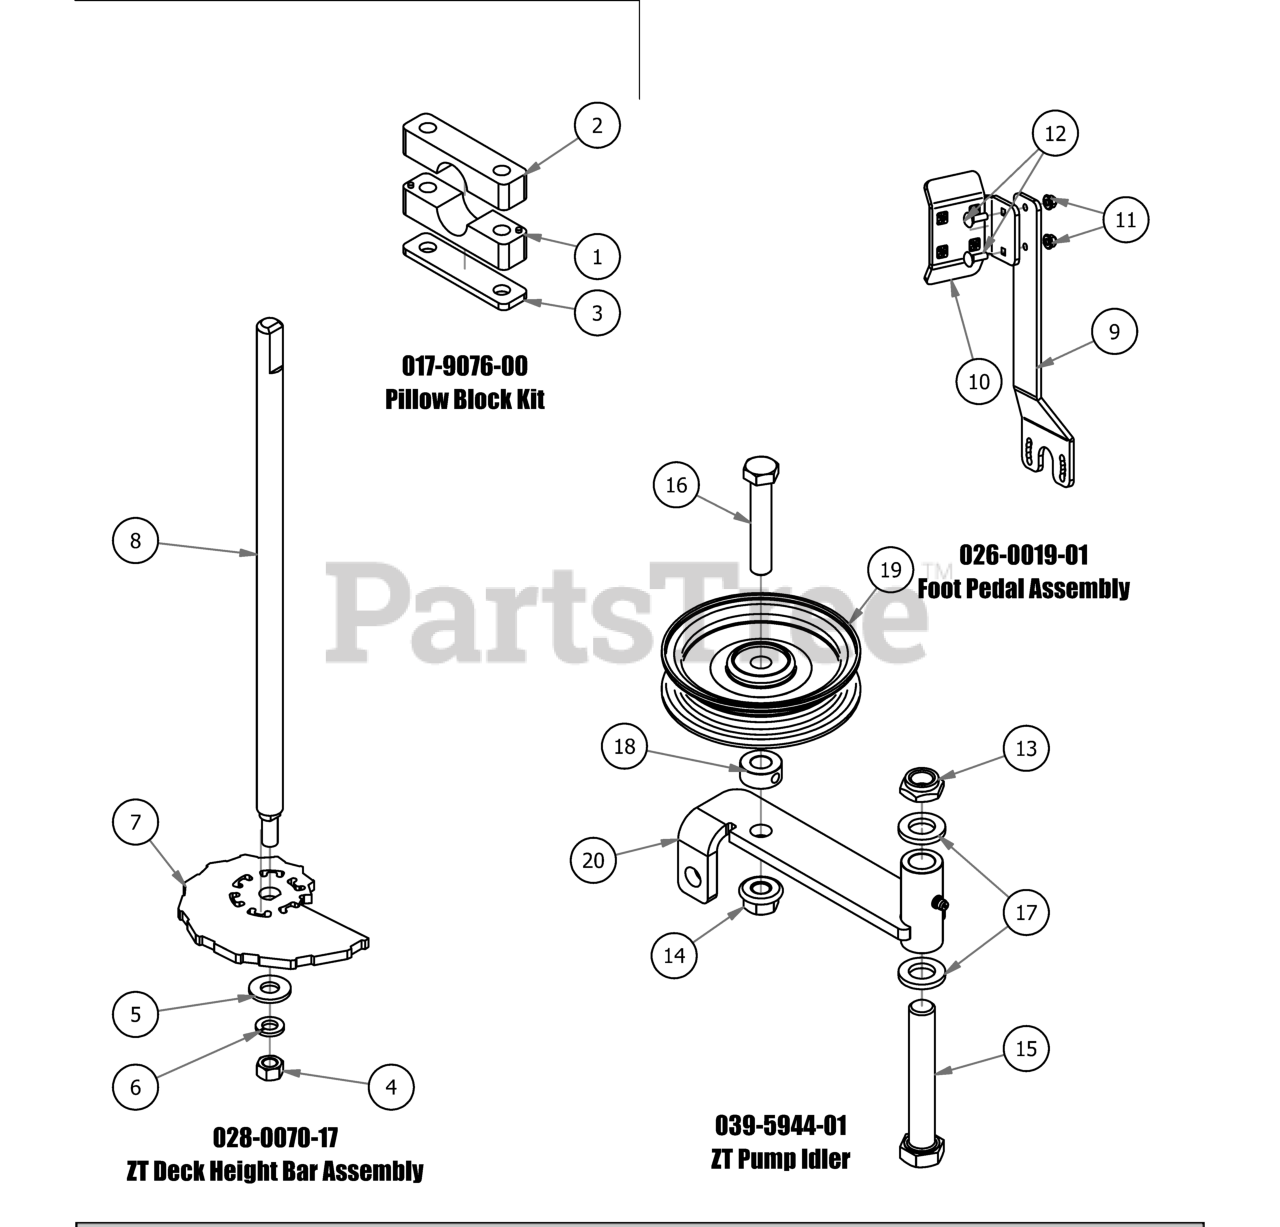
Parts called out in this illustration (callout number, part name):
1	Pillow Block MZ male
2	Pillow Block MZ female
3	Pillow Block Strap
4	3/8" Fine Threaded Jam Nut
5	3/8" Flat Washer
6	3/8" Lock Washer
7	2017 MZ/ZT Cam Plate
8	2017 Deck Height Dial Rod ZT
9	2017 MZ/ZT Deck Pedal Lever
10	2017 MZ/ZT Shallow Foot Pedal
11	5/16" Nylon Flange Nut
12	5/16" x 1" Carriage Bolt
13	5/8-11 NYLON INSERT JAM LOCKNUT ZINC
14	1/2-13 NYLON INSERT FLANGE LOCKNUT ZINC
15	5/8-11 X 4 HEX CAP SCREW (GR.8) ZINC YELLOW
16	1/2-13 X 2-3/4 HEX CAP SCREW (GR.5) ZINC
17	.635 ID X 1.120 OD X .140 THICK FLAT WASHER NYLON
18	1/2 SOLID SHAFT COLLAR (W/1 SET SCREW) ZINC
19	4 3/4" Idler Pulley
20	Pump Idler Bracket
